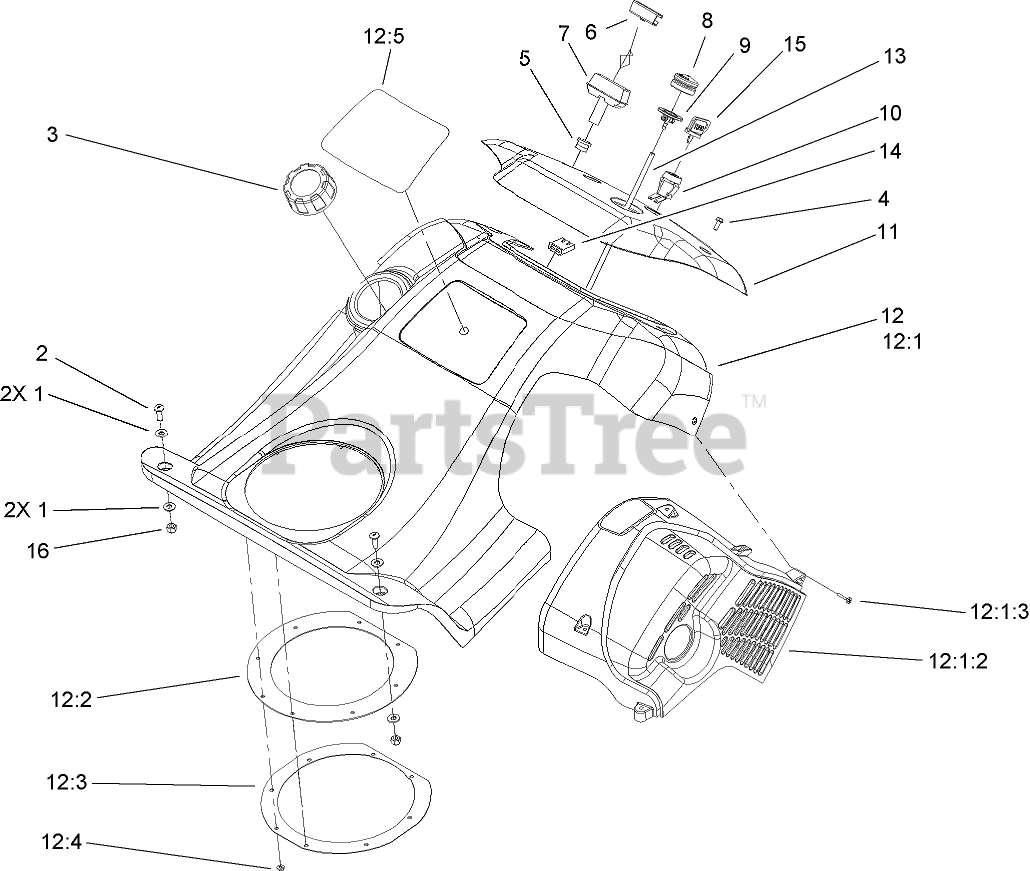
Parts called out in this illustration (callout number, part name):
1	WASHER-FLAT
2	SCREW-PPH
3	GAS CAP ASM
4	SCREW-HWH
5	GUIDE-ROPE, STARTER
6	CLIP-STARTER
7	HANDLE-START
8	BULB-PRIMER
9	BODY-PRIMER
10	SWITCH
11	PANEL-CONTROL
12	UPPER SHROUD ASM
12:1	SHROUD-UPPER
12:1:2	SHIELD-HEAT
12:1:3	SCREW-PPH
12:2	Seal-Chute
12:3	RETAINER-SEAL, CHUTE
12:4	PALNUT
12:5	DECAL-SHROUD, UPPER
13	HOSE-PRIMER
14	CONNECTOR-BODY
15	KEY-IGNITION
16	NUT-LOCK, NI
